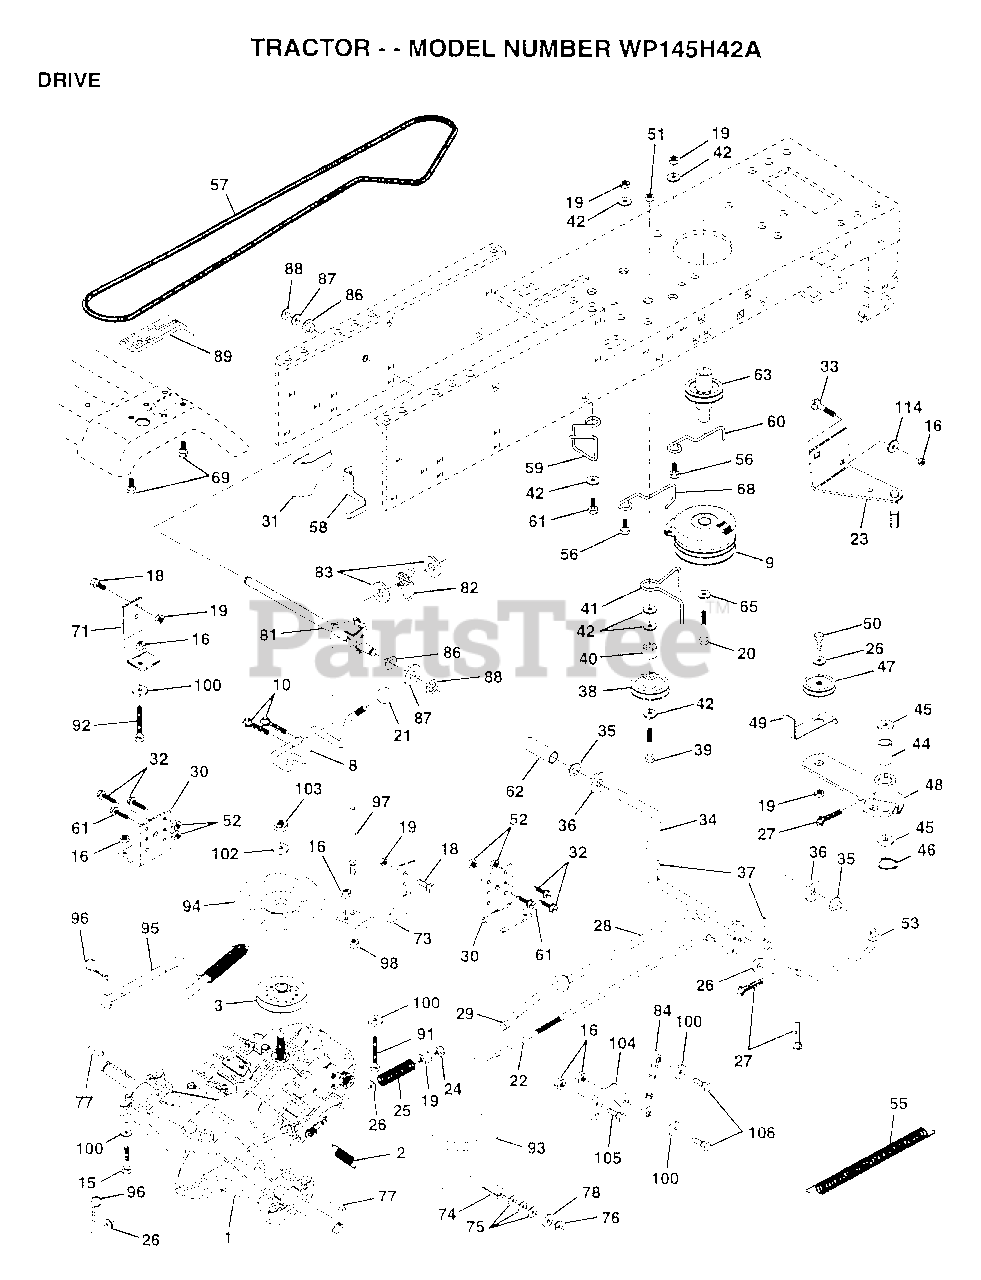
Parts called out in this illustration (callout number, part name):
2	SPRING RET BRAKE
3	PULLEY.TRANSAXLE
8	ROD SHIFT FEND YT
9	CLUTCH.ELECT.EVX.
10	PIN COTTER 1/8
15	BOLT HEX
16	NUT
18	BOLT
19	NUT
21	KNOB T (1/2-HOLE)
22	ROD.BRAKE.HYDRO.
24	NUT
25	SPRING ROD LT
26	WASHER
27	COTTER PIN
28	ROD.BRAKE.PARK.LT
29	PLUNGER CAP T
30	TRANSAXLE MTG BKT
31	"KEEPER,BELT LH T"
32	BOLT
33	BOLT
34	SHAFT.PEDAL.FOOT
35	NYLON BEARING
36	WASHER LT
38	PULLEY.IDLER.FLAT
39	BOLT
40	SPACER T
41	BELT KEEPER LT
42	WASHER
44	"LY, BEARING"
45	WASHER LT
46	KLIP RING
48	ARM IDLER
49	RETAIN BELT
53	"LINK, CLUTCH T"
55	"SPRING, RETURN LT"
57	"BELT.GD DRV 82"""
58	KEEPER BELT LH
59	KEEPER BELT CNTSP
60	KEEPER BELT ENGLH
61	SCREW
62	PEDAL COVER T
63	PULLEY.CLUTCH.EVX
65	LOCKWASHER
68	"KEEPER,BLT ENG LT"
69	SCREW HEXWSH H-L
71	STRAP TORQ LH HYD
73	STRAP TORQ RH HYD
74	SPACER SPLIT
75	WASHER
76	E-RING LT
77	SQUARE KEY
78	WASHER
82	"SPRING,TORSION"
83	WASHER
84	ROD.TIE.BALL.4.75
86	BUSHING
87	WASHER D
88	KLIP RING
92	HEX BOLT
93	"LINE FUEL HYD 4"""
94	"FAN 7"" HYDRO"
96	RETAINER M
97	BOLT KEEPER RH
98	NUT
100	WASHER M
102	WASHER BELLEVILLE
104	ARM CONTROL HYDRO
105	SCREW CAP 5/16-18
106	BOLT
114	WASHER
